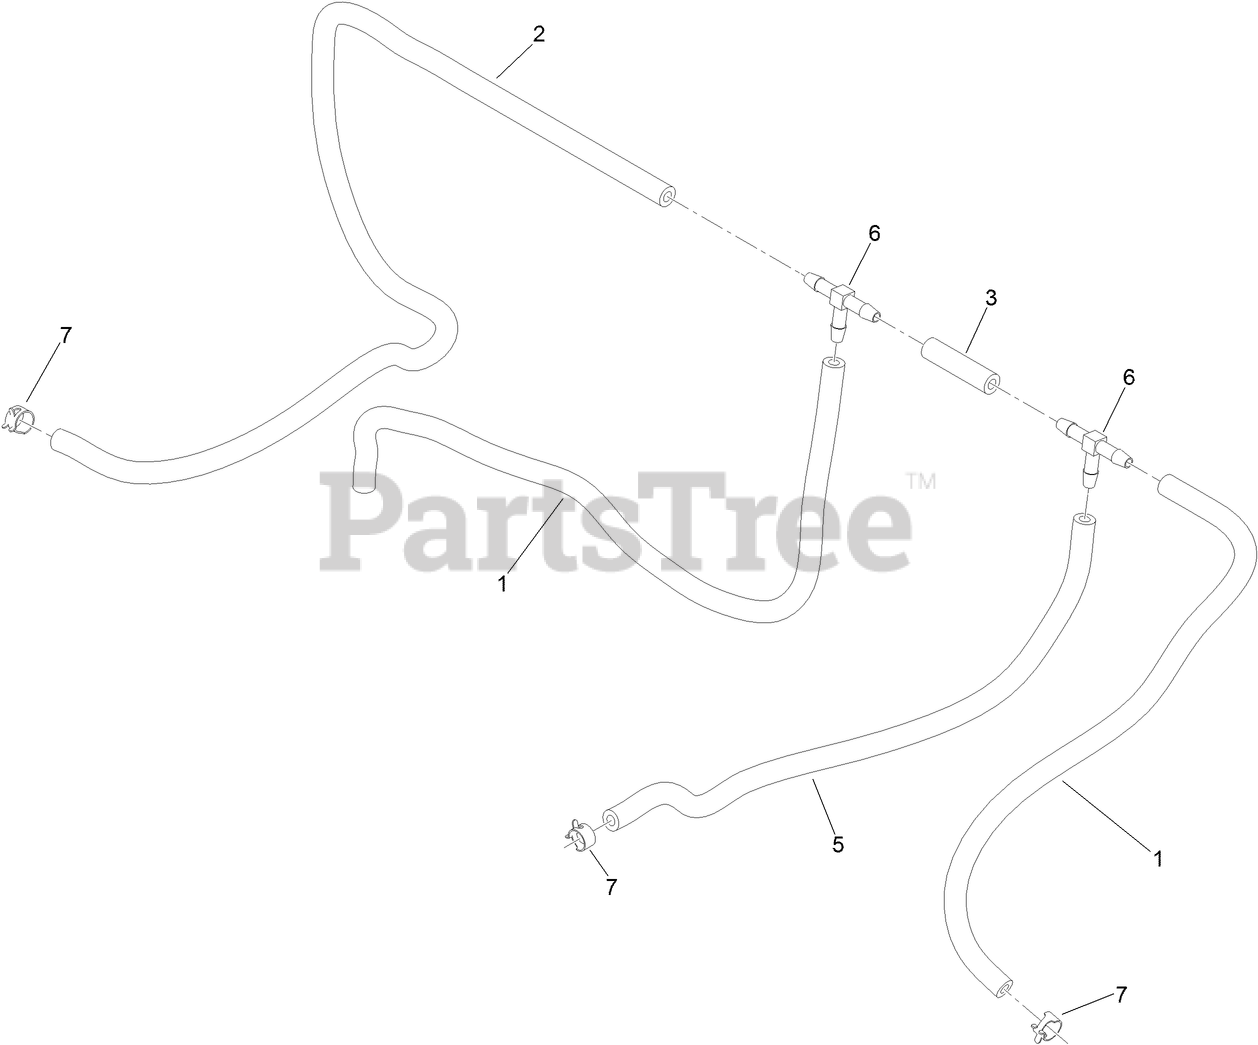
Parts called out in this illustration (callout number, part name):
1	HOSE-FUEL
2	HOSE-FUEL
3	HOSE-FUEL
5	HOSE-FUEL
6	FITTING-TEE, BARBED
7	CLAMP-HOSE
